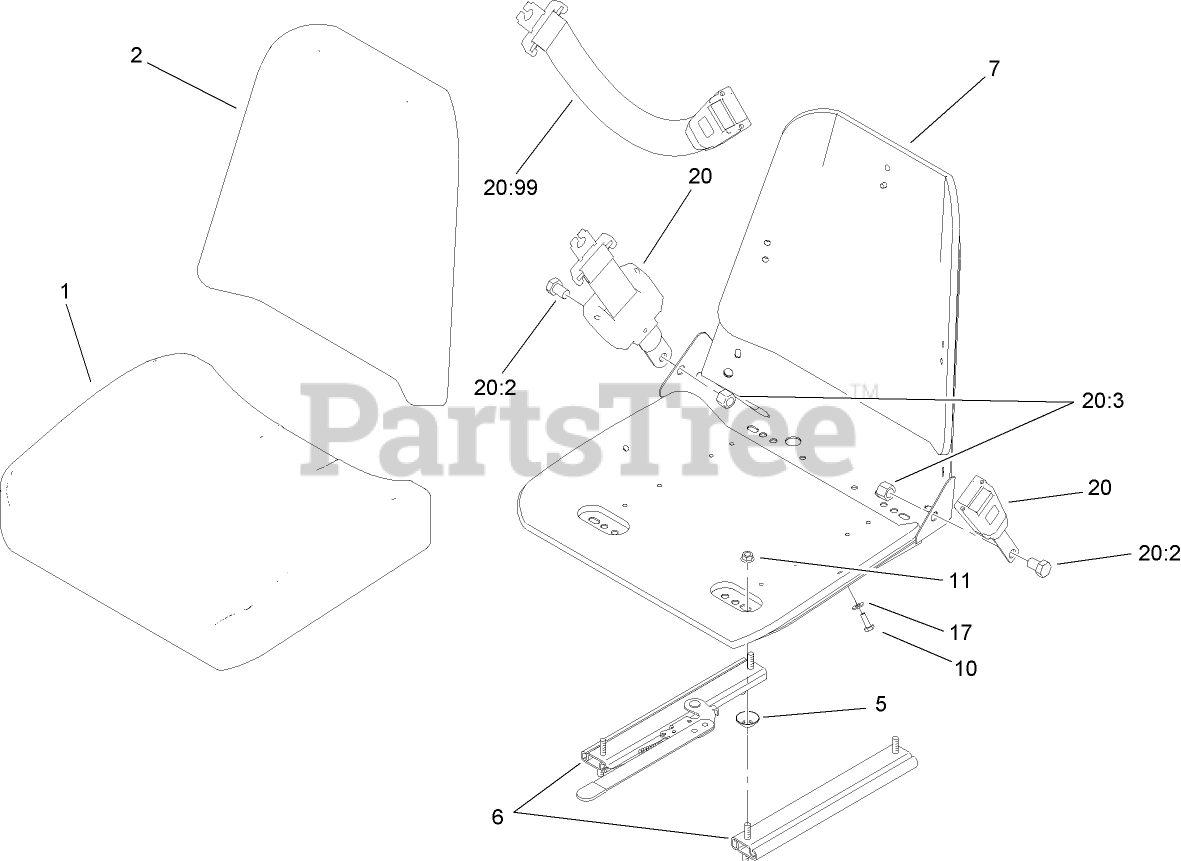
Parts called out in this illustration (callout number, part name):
1	CUSHION-SEAT, BOTTOM
2	CUSHION-SEAT, BACK
5	SPACER-TRACK
6	TRACK-SEAT
7	FRAME-SEAT
10	SCREW-HH
11	NUT-HF
17	WASHER-FLAT
20	RETRACTABLE SEATBELT KIT
20:1	SEATBELT-RETRACTABLE
20:2	SCREW-HH
20:3	NUT-LOCK
20:99	SEAT BELT EXTENSION KIT
